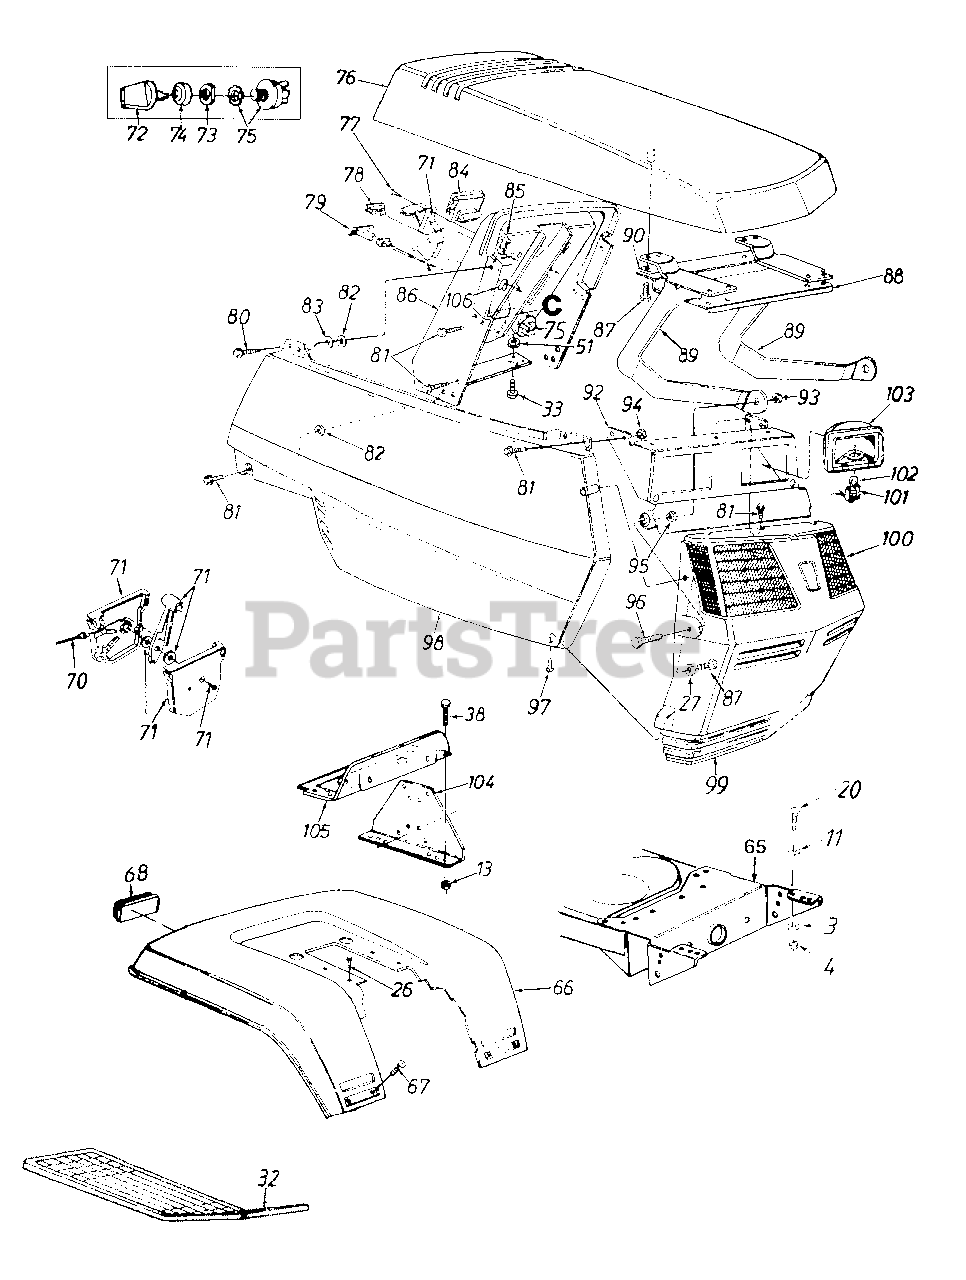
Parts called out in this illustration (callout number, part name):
11	Lock Washer 5/16" I.D.
13	Hex Sems Nut 1/4-20 Thd.
26	Hex Wash. Hd. AB-Tap Scr .5/16 x .75"
27	Flat Washer .218" I.D. x .5" O.D.
32	Rubber Foot Pad-LH
33	Hex Bolt 5/16-18 x .75" Lg.
38	Hex Bolt 1/4-20 x .62" Lg.
51	Hex Sems Nut 5/16-18 Thd.
70	Throttle Wire 18.5" Lg.
71	Throttle Control Box Assembly
72	Ignition Key
73	Ignition Switch Nut
74	Ignition Switch Cap
75	Ignition Switch
76	Hood - Red
77	Truss Mach. AB-Tap Scr. #10 x.5" Lg.
78	Light Switch
79	Choke Control 29" Lg.
80	Hex Wash. Hd. Tap Scr. 1/4 x .75" Lg.
81	Hex Tap Scr. 1/4-20 x .5" Lg.
82	Push Nut Fastener
83	Flat Washer .27" I.D. x .948"
84	Ammeter
85	Speed Nut 1/4-20 Thd.
86	Dash Panel
87	Hex Wash. Hd. B-Tap Scr. 1/4 x .75" Lg.
94	Hex Lock Nut 1/4-20 Thd.
95	Hex Jam Nut 5/16-18 Thd.
96	Hex Bolt 5/16-18 x 7/8" Lg.
97	Truss Mach. B-Tap Scr. #10 x .5" Lg.
98	Side Cover-RH - Red
99	Grille - Red
100	Lens-LH
101	Twist Lock-Lamp Socket
102	Lamp
103	Headlight Housing
